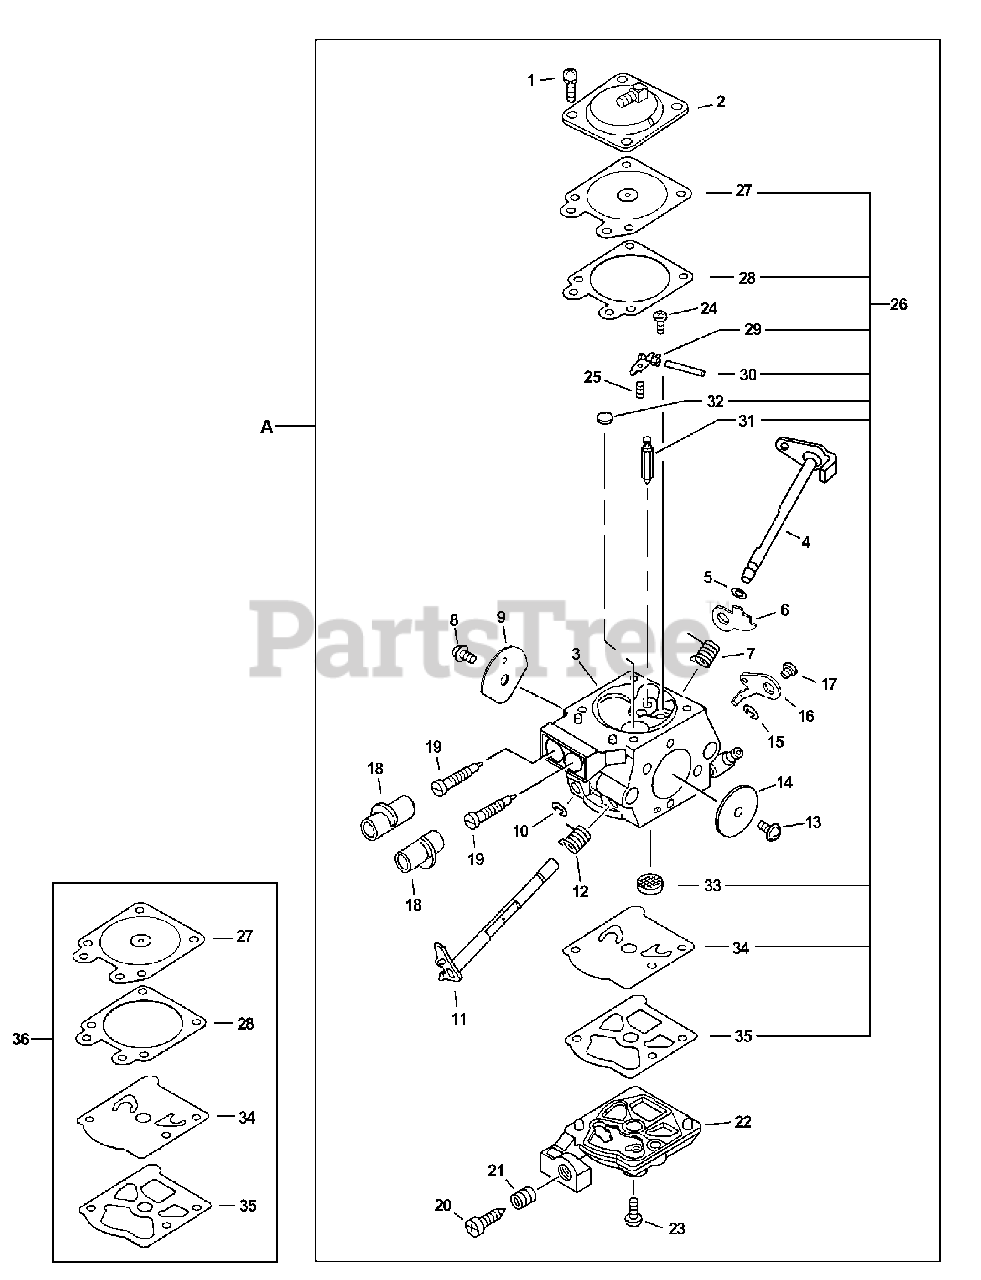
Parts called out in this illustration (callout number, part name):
2	COVER, METERING DIAPHRAGM
3	BODY, CARBURETOR
4	SHAFT, CHOKE
6	LEVER, FAST IDLE
7	SPRING, CHOKE RETURN
9	VALVE, CHOKE
11	SHAFT, THROTTLE
12	SPRING, THROTTLE RETURN
14	VALVE, THROTTLE
16	LEVER, THROTTLE
18	CAP, LIMITER
19	NEEDLE, MIXTURE
20	SCREW, IDLE ADJUST
21	SPRING, IDLE ADJUST
22	COVER ASSY, PUMP
24	SCREW, METERING LEVER PIN
25	SPRING, METERING LEVER
26	REPAIR KIT, CARBURETOR
27	DIAPHRAGM, METERING
28	GASKET, METERING
29	LEVER, METERING
30	PIN, METERING LEVER
31	VALVE, INLET NEEDLE
32	PLUG, WELCH
33	STRAINER
34	DIAPHRAGM, PUMP
35	GASKET, PUMP
36	GASKET / DIAPHRAGM KIT
A	CARBURETOR - WT-739
